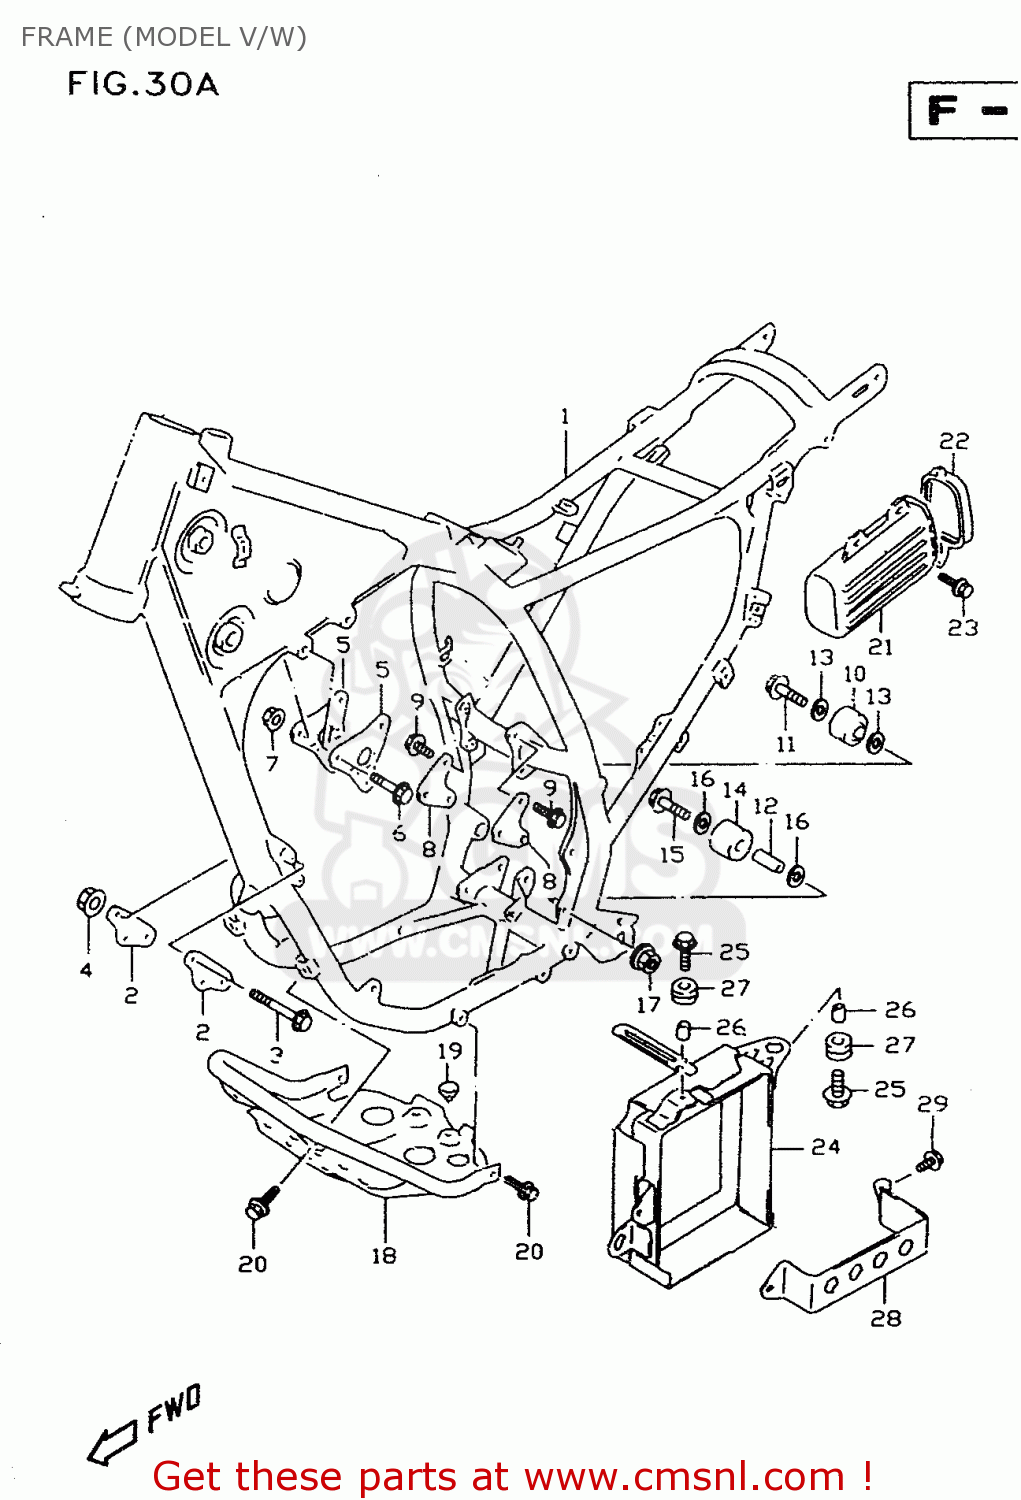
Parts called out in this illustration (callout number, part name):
1	FRAME (PURPLE)
2	PLATE,ENGINE MOUNT FR
3	BOLT(8X85)
4	NUT
5	PLATE,ENGINE MOUNT UPR
6	BOLT(8X70)
7	NUT
8	PLATE,ENGINE MOUNTING,REAR
9	BOLT(8X16)
10	ROLLER,CHAIN CONTROL
11	BOLT(8X38)
12	SPACER(8.6X12X25.5)
13	WASHER
14	ROLLER,CHAIN
15	BOLT 8X45
16	SHIM(8X12X1)
17	NUT
18	PROTECTOR,ENGINE(SILVER)
19	CUSHION
20	BOLT
21	HOLDER,TOOL
22	CAP,TOOL HOLDER
23	BOLT 6X16
24	HOLDER,BATTERY
25	BOLT(6X20)
26	SPACER(6.5X10X9)
27	CUSHION
28	COVER,BATTERY HOLDER
29	SCREW(6X10)
